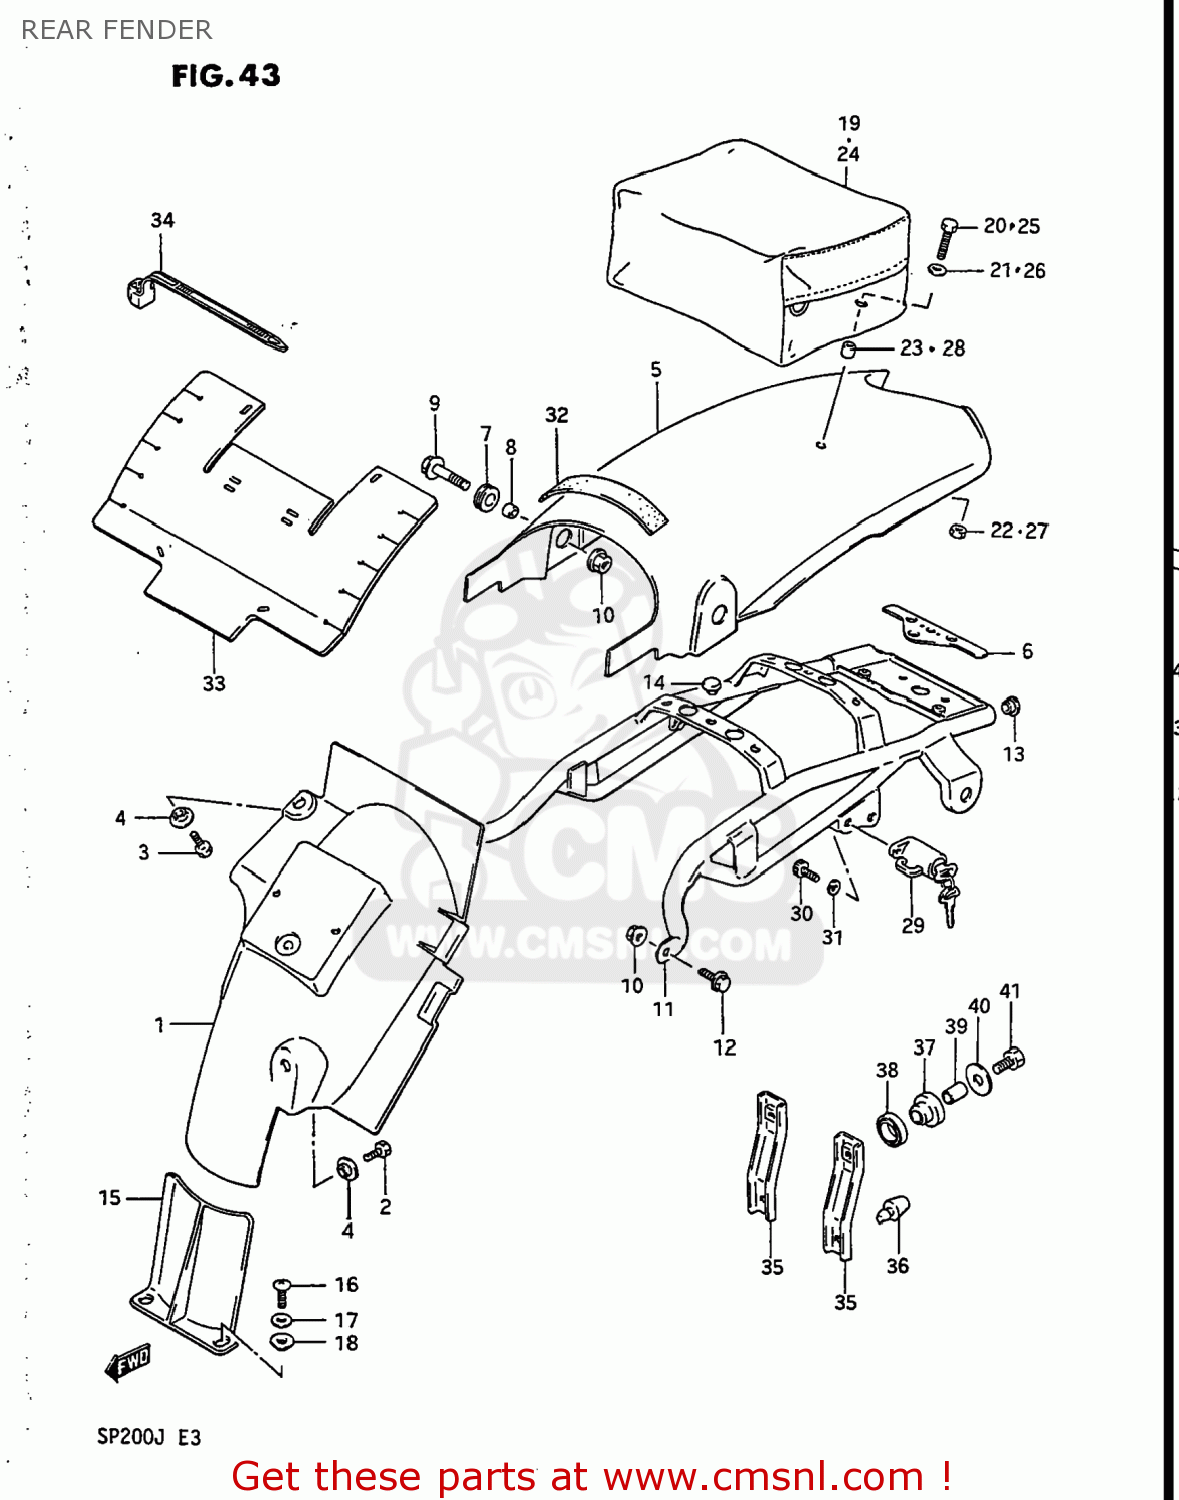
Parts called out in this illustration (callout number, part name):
1	FENDER,REAR
2	BOLT
3	BOLT 6X16
4	WASHER
5	FENDER,REAR
6	CUSHION,RR FENDER
7	CUSHION
8	SPACER (8.2X12X7.5)
9	BOLT
10	NUT
11	REINFORCEMENT,REAR FENDER
12	BOLT
13	PLUG
14	CUSHION
15	GUARD,RR UNIT MUD
16	SCREW
17	WASHER(6.5X16X1.2)
18	WASHER,LOCK
19	BAG SET,SEAT TAIL
20	BOLT
21	WASHER
22	NUT
23	SPACER (6.1X9X9)
24	BAG ASSEMBLY,SEAT TAIL
25	BOLT
26	WASHER
27	NUT
28	SPACER (6.1X9X9)
29	LOCK ASSEMBLY,HELMET
30	BOLT 6X11
31	WASHER,LOCK
32	CUSHION(25X185X15)
33	FLAP,AIR CLEANER MUD
34	CLAMP(L:125)
35	HOLDER,LICENSE PLATE CUSHION
36	CUSHION
37	CUSHION
38	CUSHION
39	SPACER(6.4X9X17)
40	WASHER
41	BOLT
